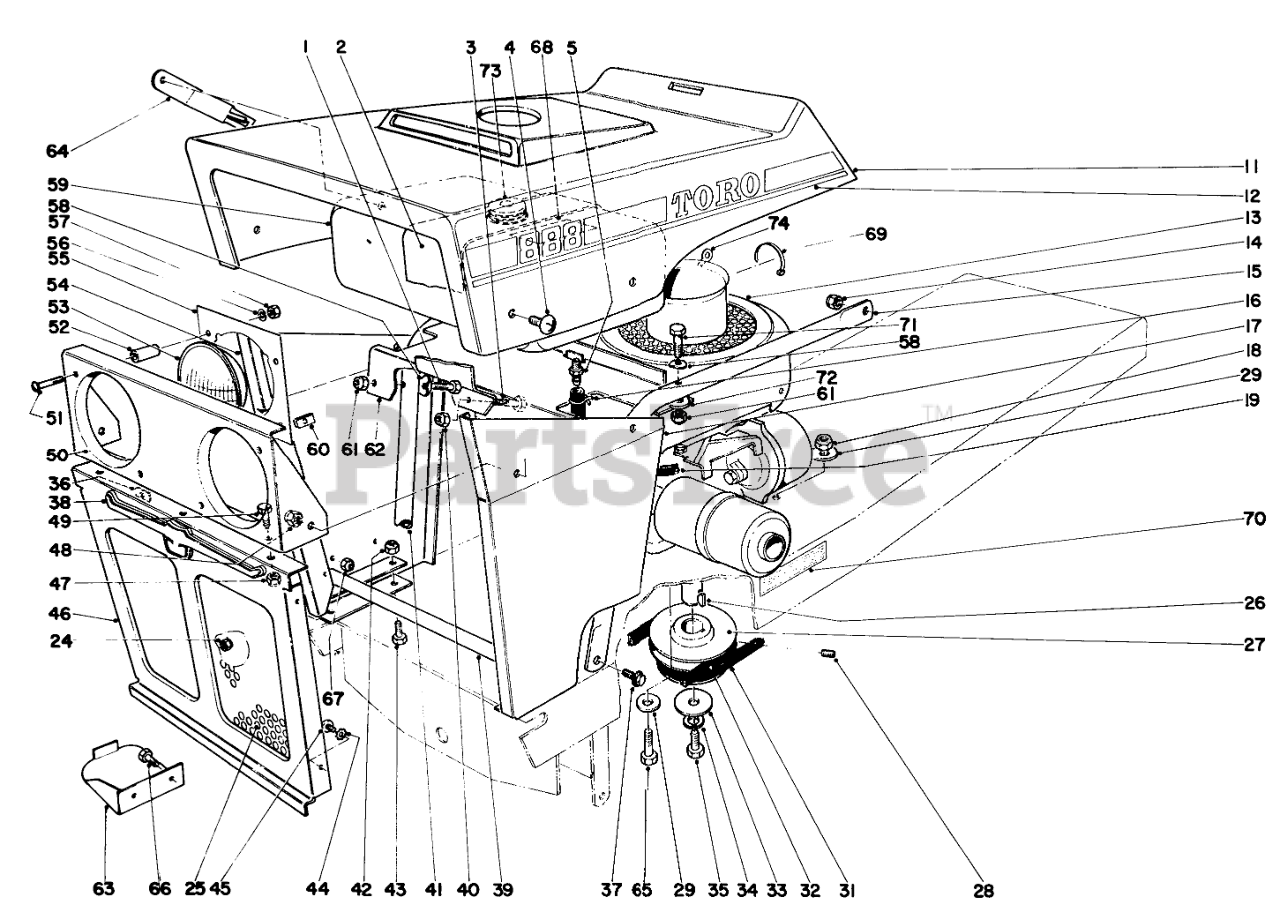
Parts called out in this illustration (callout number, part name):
1	SCREW-HH
2	Strap Gas Tank
3	SCREW-HH
4	Round Head Screw
5	Hose Connector
12	Decal Hood Left
13	Engine
14	NUT-LOCK, CONE
15	Support Gas Tank Left
16	CLAMP-HOSE
17	Skin Left Front
18	Nut
24	NUT-LOCK, NI
25	Grille Panel
26	KEY-WOODRUFF
27	Pulley Engine
28	SCREW-SET, HSH
29	WASHER-PLAIN
31	Belt
32	V BELT PTO
33	WASHER-FLAT
34	Lockwasher
35	SCREW-HH
36	Timmerman Nut
38	Bullshead
39	Hinge
41	Support Gas Tank Right
43	SCREW-HH
44	WASHER-LOCK, EXT
46	Grille
48	Nut
49	SCREW-HH
50	Headlamp Panel
51	Round Head Pan Screw
52	Spacer
53	HEAD LAMP
54	Skin Right Front
55	Headlight Holder
56	WASHER-LOCK/SP
57	NUT-HEX
58	WASHER
59	Gas Tank
60	NUT-CLIP,U
62	Bracket Gas Tank
63	Trimmer Support
64	Bracket Trimmer
65	SCREW-HH
66	SCREW-HH
67	NUT-LOCK, CONE
68	Decal
69	CONTROL WIRE CLIP
70	Decal
71	SCREW-HH
72	Spacer
73	Gage-Fuel
